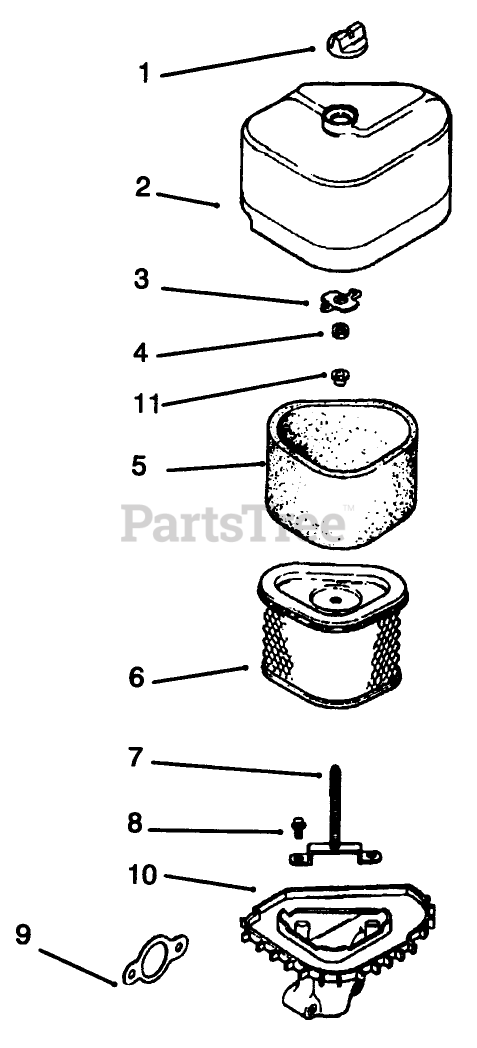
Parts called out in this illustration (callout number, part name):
1	Knob-Air Cleaner Cover
2	Cover-Air Cleaner
3	Nut-Wing
4	Washer
5	Element-Air Cleaner (Only On: 72042, 72043, 72062, 72063)
6	Precleaner-Element (Only On: 72042,72043,72062,72063)
7	Stud M-6x1.0x66
8	Screw-Mounting Plate (Only On: 72042, 72043, 72062, 72063)
9	Gasket-Air Cleaner (Only On: 72042, 72043, 72062, 72063)
10	Base-Air Cleaner (Incl.
11	Grommet
